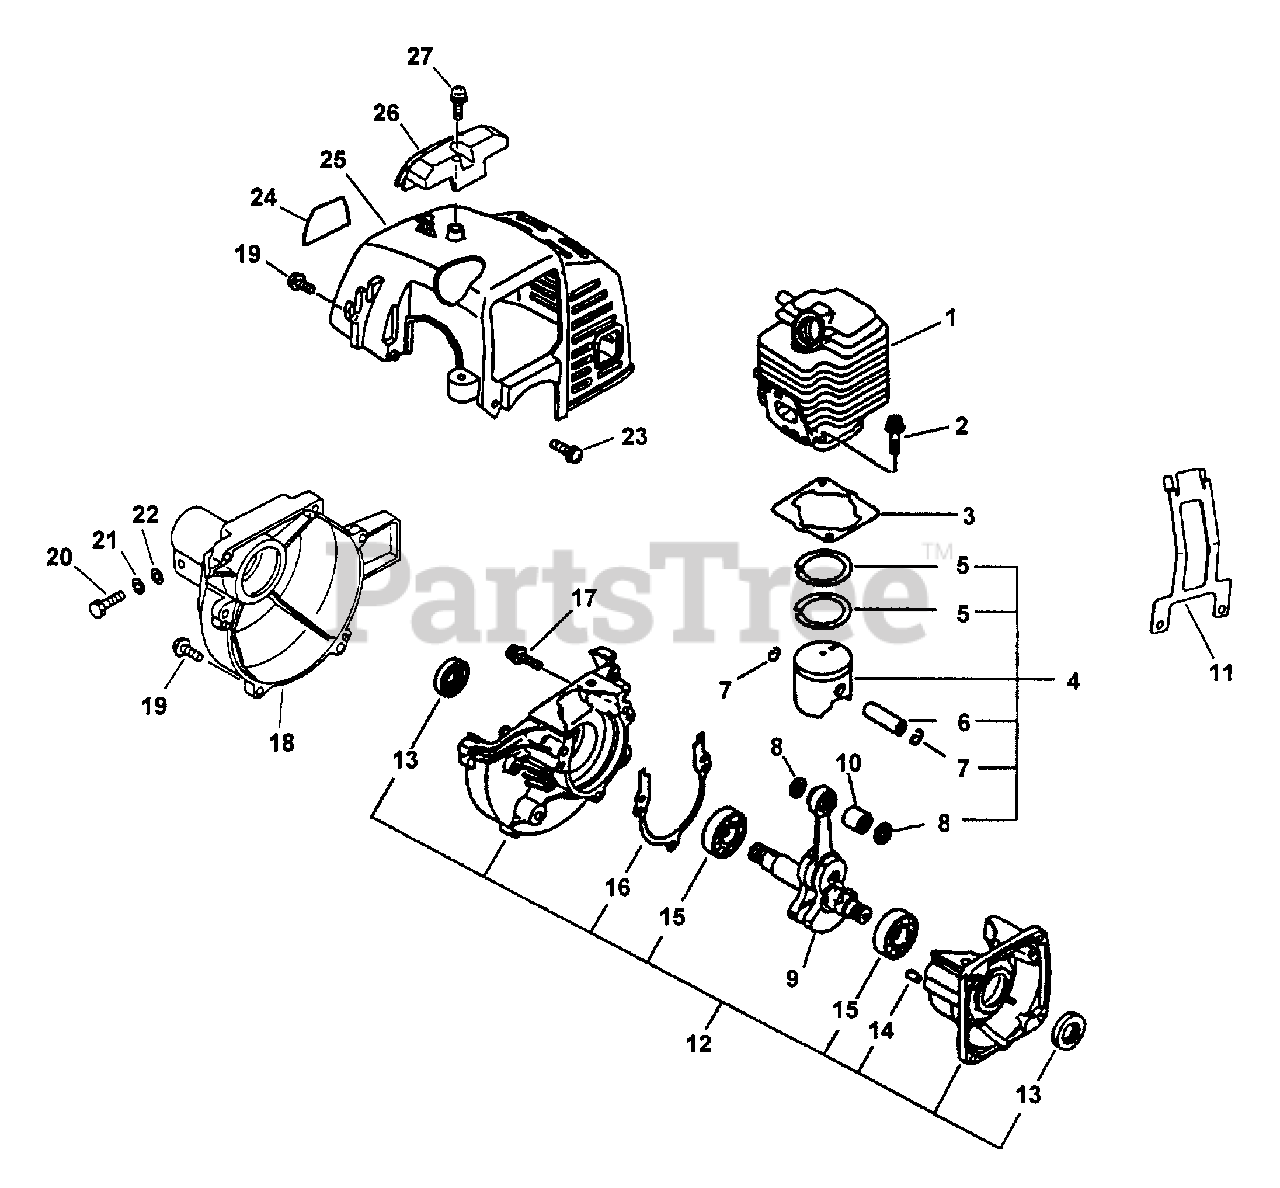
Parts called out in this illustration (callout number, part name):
1	CYLINDER
2	BOLT 5×22
3	GASKET, CYLINDER
4	PISTON KIT
5	RING, PISTON
6	PIN, PISTON 8
7	RING, SNAP
8	WASHER, THRUST
9	CRANKSHAFT ASSY
10	BEARING, NEEDLE
11	GUARD, ENGINE
12	CRANKCASE KIT
13	SEAL, OIL 12
14	PIN, LOCATING 4
15	BEARING, BALL - 6201 C3
16	GASKET, CRANKCASE
17	BOLT 5×28
18	CASE, FAN
19	BOLT 4×16
20	BOLT 5×25
21	WASHER, SPRING 5
22	WASHER, FLAT 5.5×10×0.8
23	SCREW 4×12
24	LABEL - MODEL
25	COVER, ENGINE - ORANGE
26	GUARD, TOP - BLACK
27	SCREW 5×16
